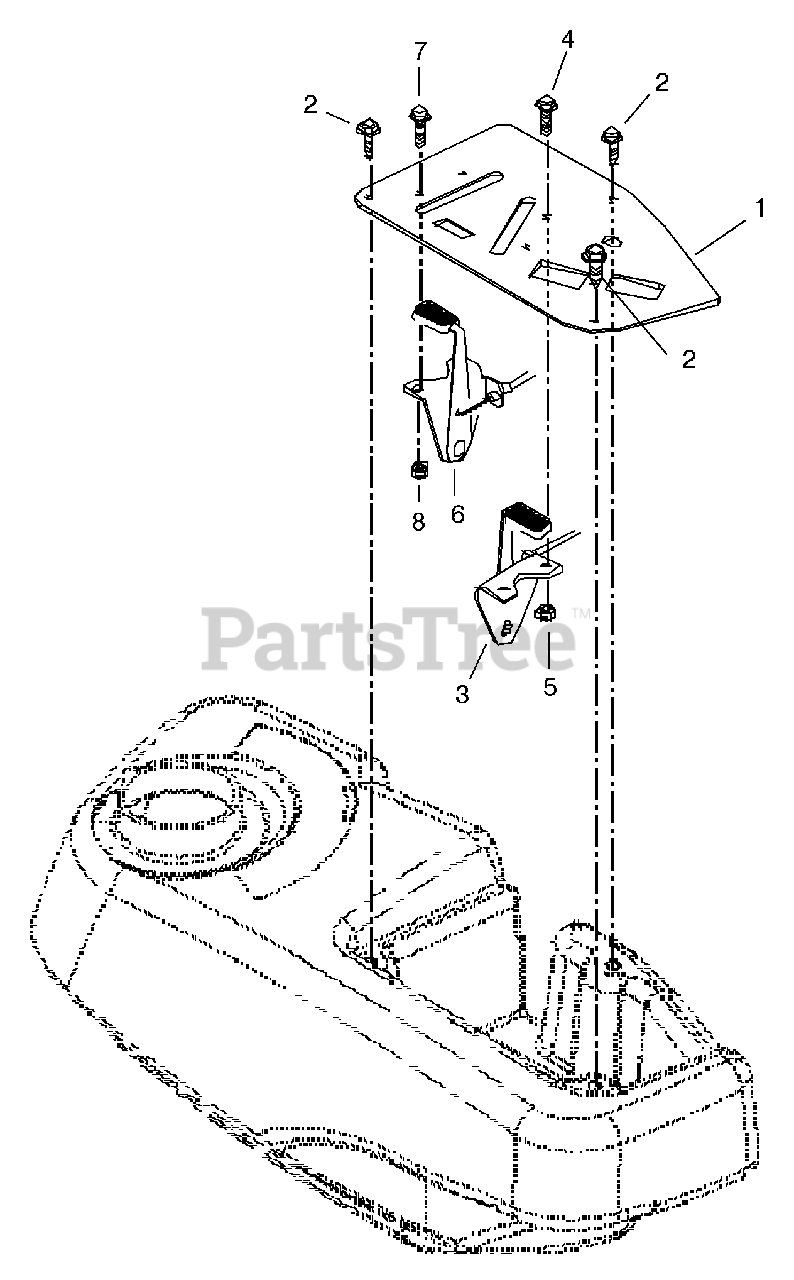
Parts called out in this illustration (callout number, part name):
1	Panel-Control-Kohler
2	Screw-Machine 10-24 x .50 Hex Washer Head
3	Throttle Control Kohler
4	Screw-Machine 10-24 x .50 Hex Washer Head
5	Nut-Locking-Nylon 10-24 With Insert
6	Choke Control-Kohler
7	Screw-Machine 10-24 x .50 Hex Washer Head
8	Nut-Locking-Nylon 10-24 With Insert
